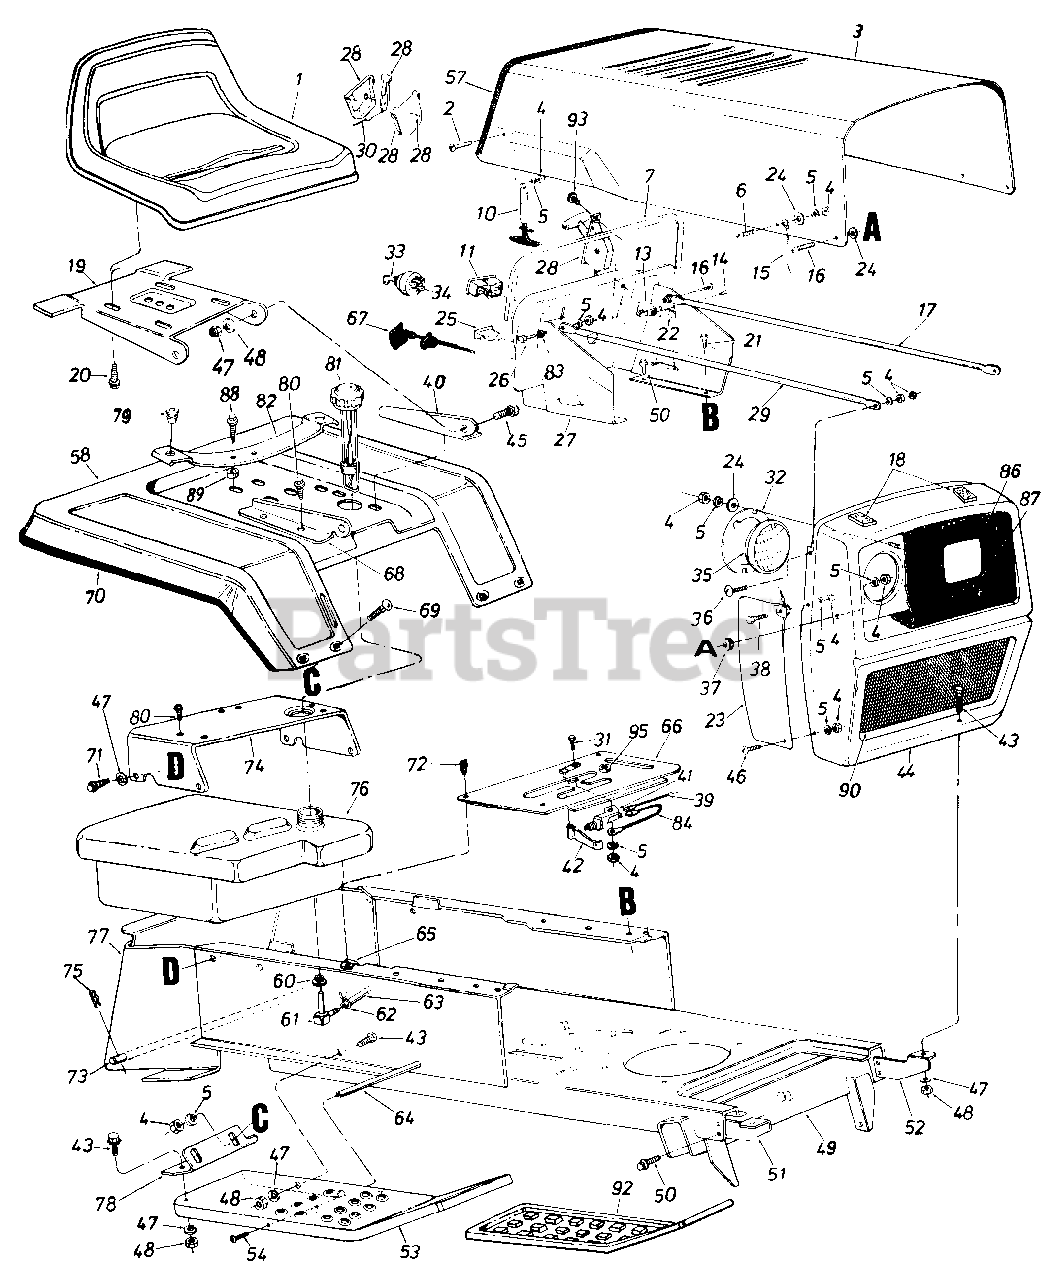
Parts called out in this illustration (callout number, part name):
1	Seat Assembly
2	Truss Mach. Scr. 1/4-20 x .50" Lg.'
5	L-Wash. 1/4" Scr.
6	Truss Mach. Scr. '/4-20 x .50" Lg.
7	Vinyl Molding Strip-29"
10	Hood Latch Ass'y.
11	Ammeter
13	Circuit Breaker 8 Amp.
14	Hex Tap Scr. #10 x .50" Lg.
15	Hood Stop
16	Truss Mach. Scr. 1/4-20 x .75" Lg.
17	Grille Positioning Rod
18	PVC Foam Strip 1/2 x 1.OO" x 2.00" Lg.
20	Hex Wash. Hd. AB-Tap Scr. 3/8 x .75" Lg.
21	Hex Thd. Rolling Scr. 1/4" x . 50" Lg .
22	Speed Nut #10Z
23	Grille Side Panel-R.H.
23	Grille Side Panel-L.H.
24	Fl-Wash. 1/4" I.D.
25	Light Switch
26	Truss Hd. Scr. 1/4-20 x 1.00" Lg.
27	Dash Panel Ass'y.
28	Throttle Control Box Comp.
29	Grille Positioning Rod
30	Throttle Control Cable
31	Hex Bolt 1/4-20 x .50" Lg.
32	Head Lamp Retainer
33	Ignition Key
34	Ignition Switch
35	Head Lamp
36	Truss Machine Scr. 1/4-20 x .75" Lg.
37	Rubber Wash. .50" I.D. x 1.00 O.D. x .25 Thk.
38	Truss Mach. Scr. 1/4-20 x .50" Lg.
39	Reverse Lockout Wire Harness
40	Seat Bracket-L.H.
41	Safety Switch
42	Switch Actuator Spring Lever
43	Hex Scr. 5/16-18 x .75" Lg.
44	Grille Ass'y.
45	Shld. Bolt .437 Dia. x .162 Lg.
46	Truss Mach. Scr. 1/4-20 x .50" Lg.
47	L-Wash. 5/16" I.D.
48	Hex Nut 5/16-18 Thd.
49	Lower Frame Ass'y.
50	Hex Thd. Rolling Scr. 5/16" x.75" Lg.
51	Grille Mount Brkt.-R.H.
52	Grille Mount Brkt.-L.H.
53	Running Board-R.H.
53	Running Board-L.H.
54	Truss Mach. Scr. 5/16-18 x 75" Lg.
54	Hex Cent. L-Nut 5/16-18 Thd.
54	Bell-Wash. .34" I.D. x .88 -O.D.
57	Vinyl Moulding Strip-30"
61	90ø Nipple
62	Hose Clamp 3/8"
63	Gas Line 46" Lg.
64	Running Board Rod
65	Speed Nut #10-24
66	Transmission Cover Ass'y.
67	Choke Control Comp.
68	Seat Bracket-R.H.
69	Carr. Bolt 1/4-20 x .50" Lg.
70	Trim Strip-81" Lg.
71	Hex Thd. Rolling Scr. 5/16-24 x .75" Lg.
72	Truss Hd. Scr. #10 x .50" Lg.
73	Hitch Rod
74	Seat Mounting Channel
75	Internal Cotter Pin
76	Gas Tank
77	Hitch Plate
78	Fender Brkt.-R.H.
80	Hex Wash. Hd. Self-Tap Scr. 5/16-18 x .50" Lg.
81	Gas Gauge
82	Seat Spring
83	External Wash. 1/4" I.Dt
84	Electric Wire
86	Headlight Bezel
87	Hex Wash. Hd. F-Tap Scr. #8-32 x .38" Lg.
88	Hex Self-Tap Scr. 5/16-18 x 1.25" Lg.
89	Spacer
90	Grille Screen
92	Foot Pad
93	Truss Mach. AB-Tap Scr. #10 x .50" Lg.
95	Snap Bushing
